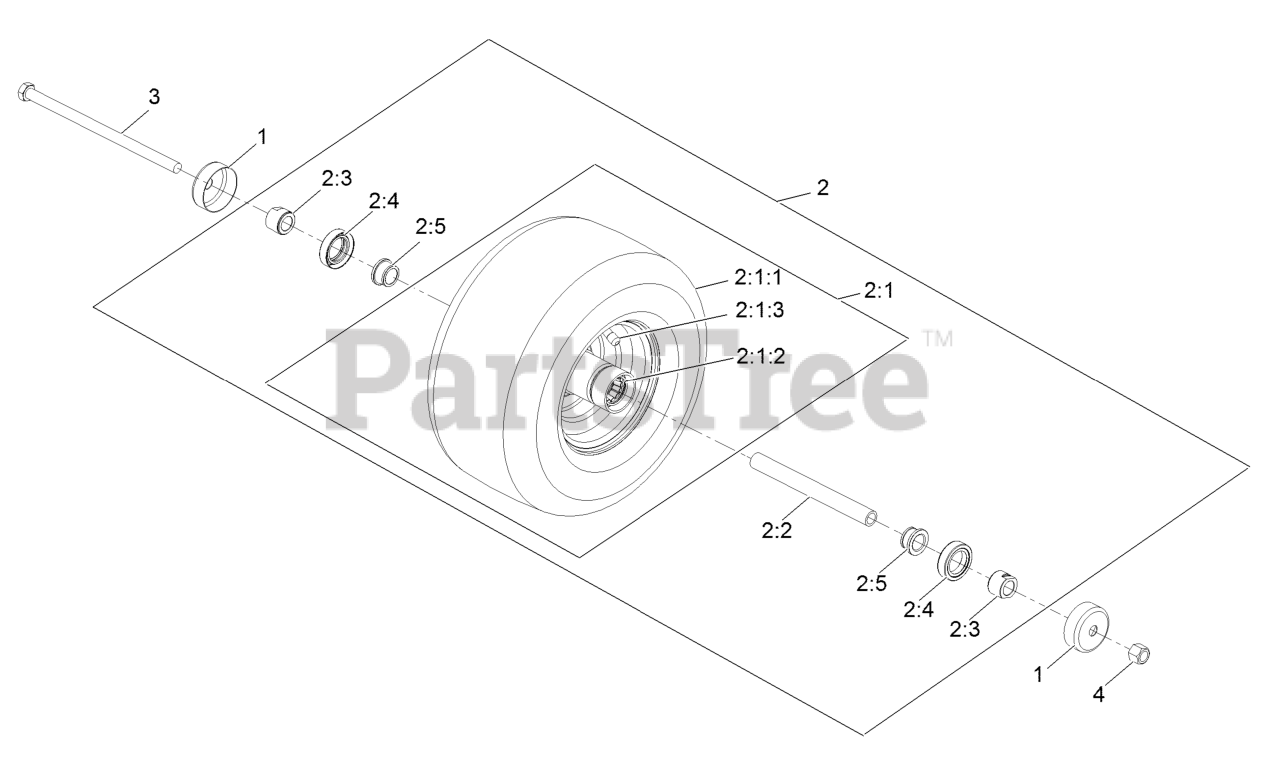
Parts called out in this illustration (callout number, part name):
1	GUARD-SEAL
2	Wheel ASM
2:1	Wheel And Tire ASM
2:1:2	BEARING-CUP
2:1:3	VALVE
2:3	SPACER-NUT
2:4	SEAL-CASTER
2:5	BEARING-CONE, TAPERED ROLLER
3	SCREW-HH
4	NUT-LOCK, NI
